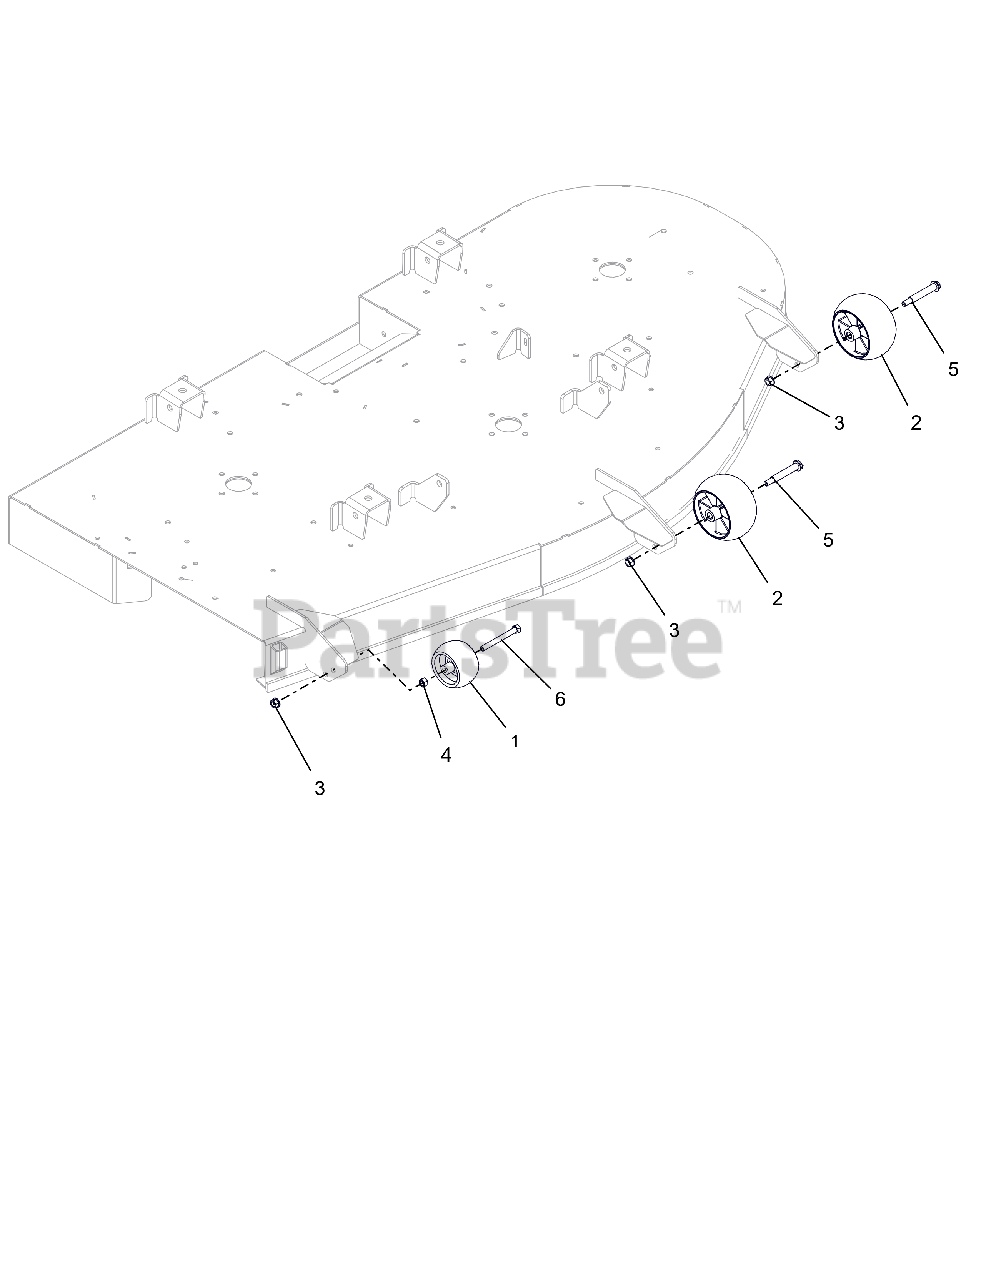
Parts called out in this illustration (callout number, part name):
2	ANTI-SCALP WHEEL - 5X OS
3	NUT-LK-TOP-FLG .38-16 ZC120
4	@NUT-HEX .38-16 YWZC
5	BLT-SHLDR .38-16X2.50 HWH G5
6	BLT, HEX .38-16X3.50 G5 ZCC
